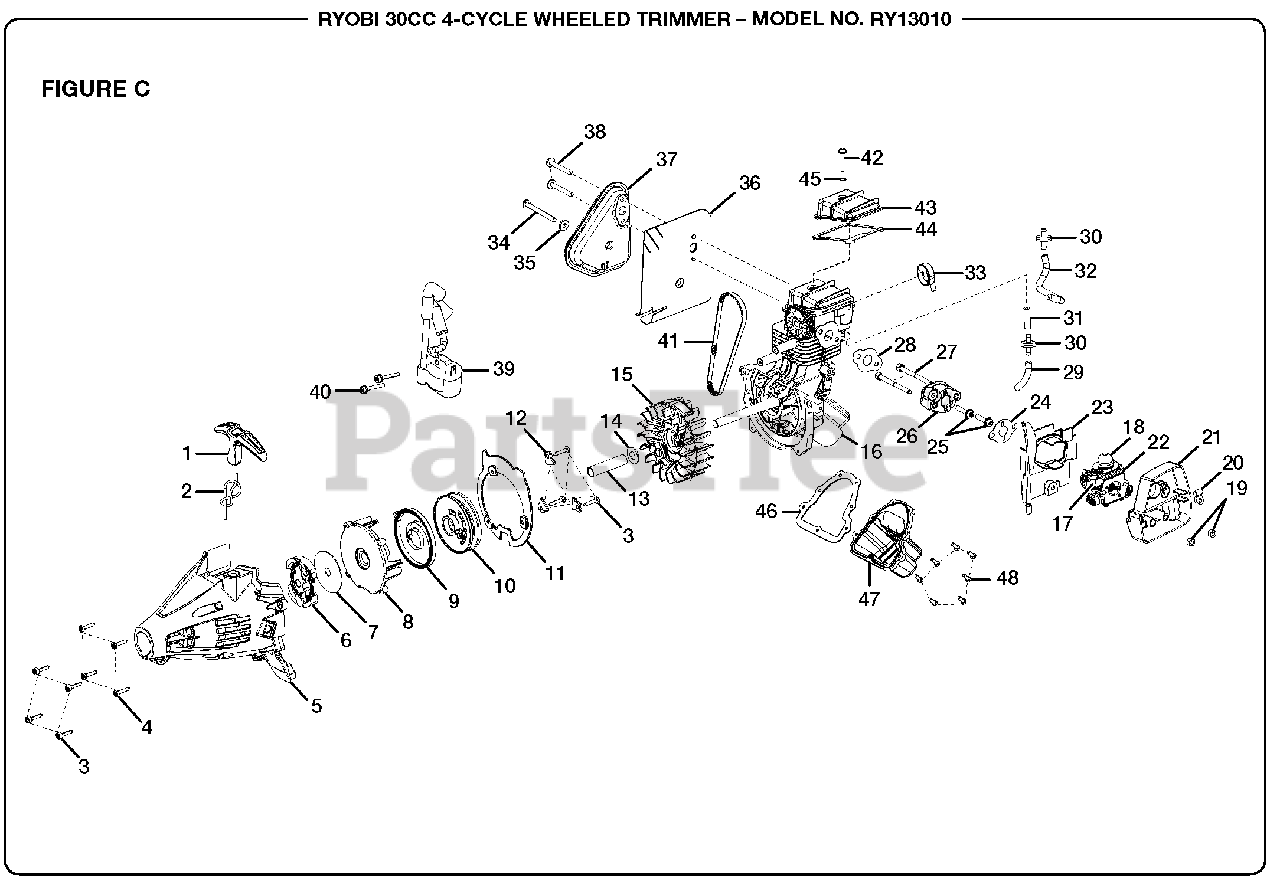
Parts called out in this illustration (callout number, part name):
1	Starter Grip
2	Starter Rope
3	Screw (M4 x 18 mm)
4	Screw (M4 x 16 mm)
5	Starter Housing Assembly
6	Clutch Assembly
8	Starter Baffle
9	Spring & Container
12	Pulley Retainer
13	Spacer Tube
14	Washer
15	Flywheel Assembly
16	Short Block Assembly (Incl. Key Nos. 41-48)
17	Choke Lever
18	Primer Bulb
19	Hex Nut (M5)
20	Loop Clamp
21	Air Box Base
22	Carburetor Assembly (Incl. Key Nos. 17-18)
23	Air Baffle
24	Carburetor Gasket
25	Screw (M5 x 23 mm)
27	Bolt (M5 x 58 mm)
28	Heat Dam Gasket
29	Breather Hose
30	Check Valve
31	Breather Hose
32	Breather Hose
33	Breather Fitting
36	Muffler Gasket
37	Muffler Assembly
38	Muffler Bolt (M5 x 42 mm)
39	Ignition Module
40	Screw (M4 x 19 mm)
41	Timing Belt
42	Screw (M4 x 27 mm)
43	Cam Cover
48	Screw (M4 x 12 mm)
